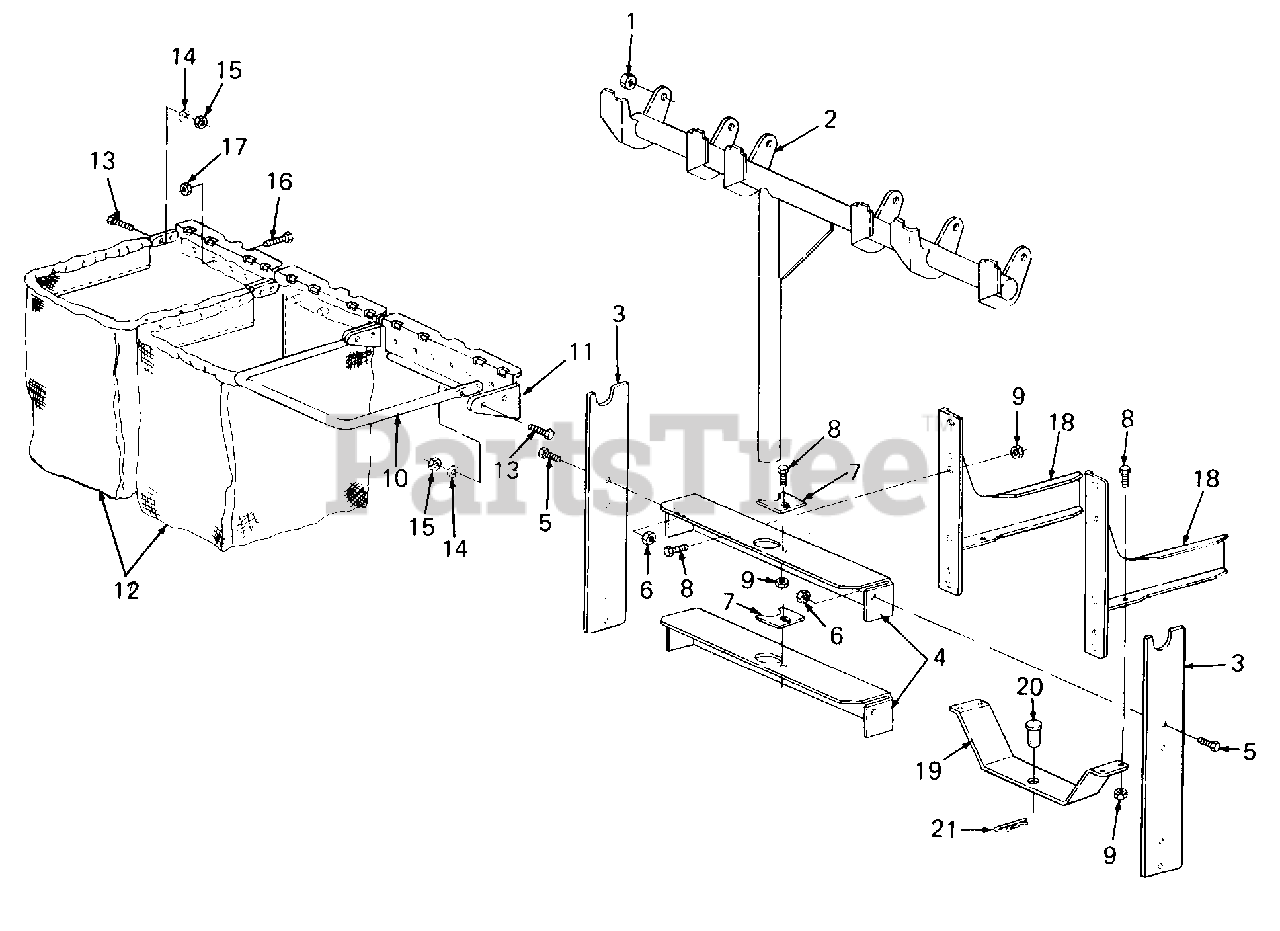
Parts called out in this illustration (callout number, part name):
1	Nut, Hex Flanged Lock, 3/8-16
6	L-Nut, Flange Top Hex, 5/16-18 GR5
8	Screw, Hex, 1/4-20 x.62 Lg GR5
9	Nut, Hex Flange Top Locknut, 1/4
10	Frame, Catcher Bag
12	Bag, Grass Catcher
13	Screw, Hex, 1/4-28 x.75 Lg
14	Washer, Lock, 1/4
15	Nut, Hex, 1/4-28
16	Screw, Truss Mach., #10-24 x .38 Lg
17	Nut, Hex Sems, #10-24
20	Pin, Clevis, .62 Dia
21	Pin, Internal Cotter
